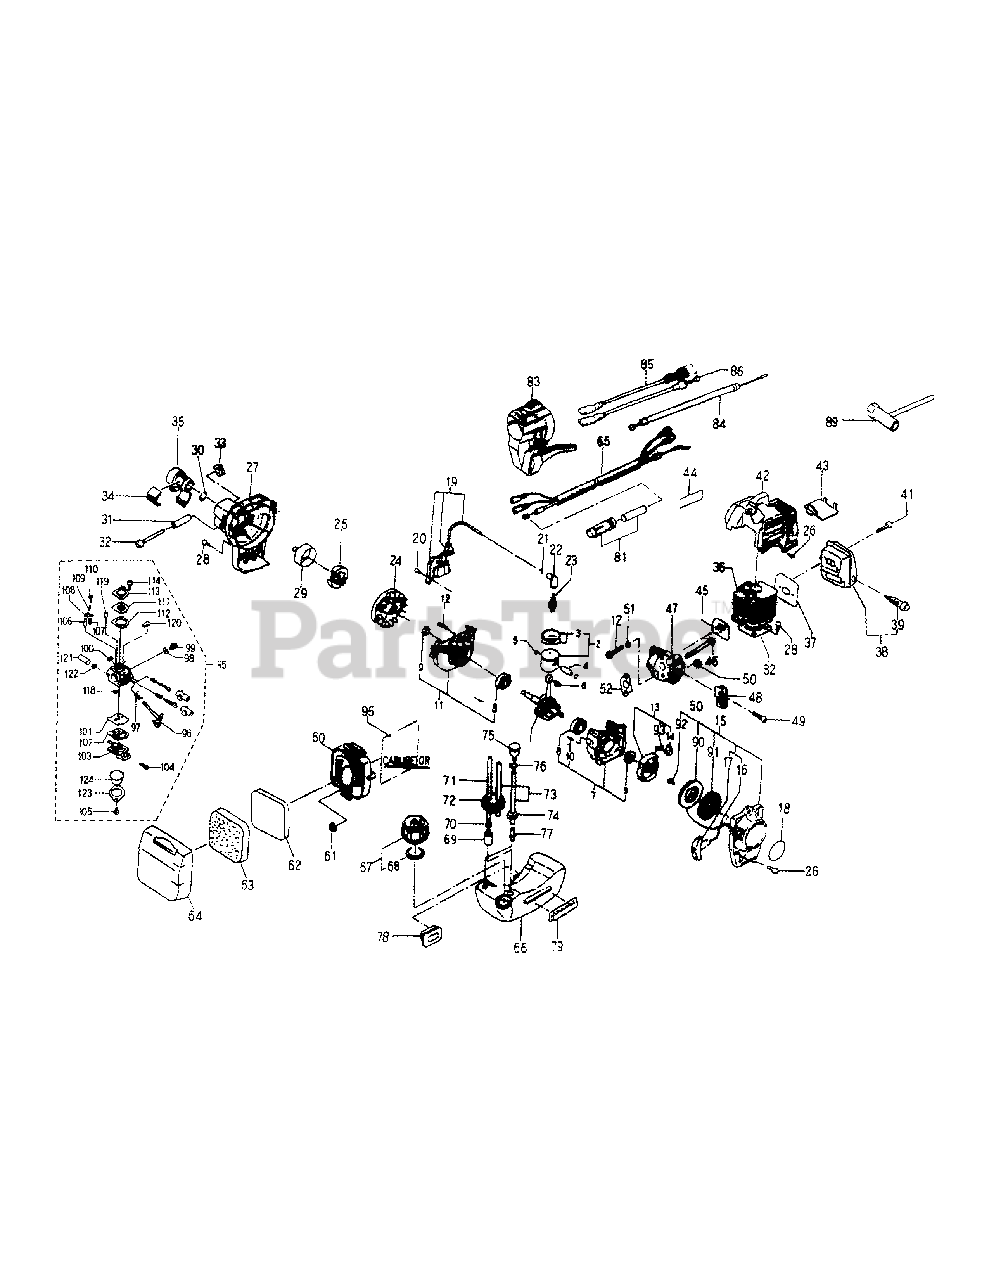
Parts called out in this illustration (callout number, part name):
2	Piston Assembly
3	Ring, Piston
5	Clip, Piston Pin
6	Needle Bearing
7	Crankcase Assembly
8	Ball Bearing:6201
11	Crankcase Assembly
13	Pulley Assembly, Starter
15	Recoil Assembly
16	Rope, Starter
17	Knob, Starter
19	Coil Assembly, Ignition
23	Spark Plug
24	Flywheel, Magneto
25	Clutch Assembly
26	Bolt; M5 x 20
27	Housing Blower
28	Bolt; M5 x 16
29	Drum, Clutch
30	Snap Ring
32	Bolt; M5 x 30
37	Gasket, Muffler
41	Bolt; M5 x 48
42	Cowling, Cylinder
43	Baffle Plate
45	Gasket, Insulator
46	Bolt; M5 x 56
49	Bolt; M5 x 12
51	Washer
60	Case, Air Silencer
62	Element (B), Filter Air
63	Element (A), Filter Air
65	Wire complete, Throttle
67	Cap Assembly, Fuel Tank
69	Filter, Fuel
71	Hose
73	Hose
75	Valve Assembly, reversing
79	Rubber
81	Holder, Wire
83	Lever assembly, Throttle
84	Wire, Throttle
85	Harness, Wire
86	Harness, Wire
91	Spring, Spiral
93	Spring, Return
95	Carburetor Assembly
96	Shaft, throttle
98	Valve, Throttle
101	Diaphragm, Pump
103	Base Assembly, Primer
106	Valve, Float
111	Diaphragm, Metering
113	Cover
119	Nozzle, Capsule
121	Seat Assembly, Valve
